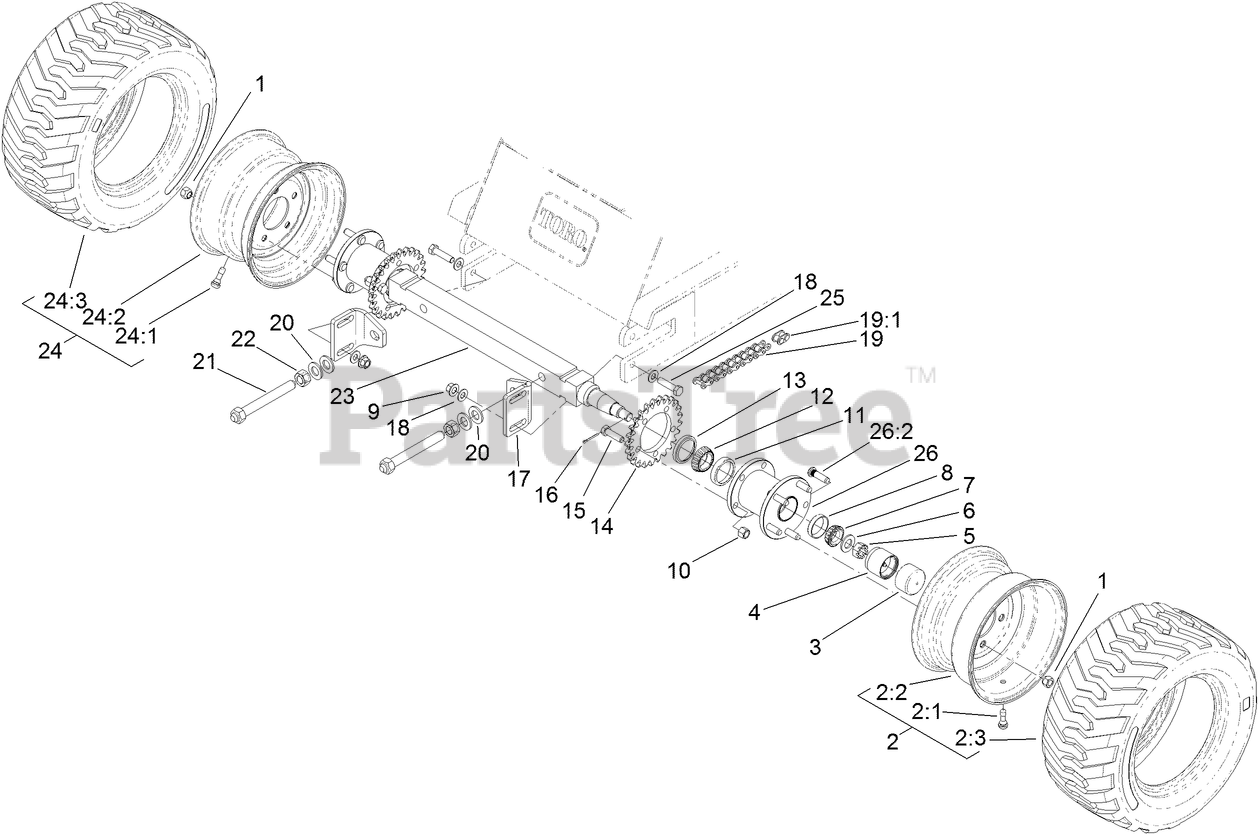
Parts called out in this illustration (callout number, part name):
1	NUT-LUG
2	LH WHEEL AND TIRE ASM
2:1	STEM-VALVE
2:2	WHEEL
3	CAP-PROTECTOR, BEARING
4	PROTECTOR-BEARING
5	NUT-HEX, SLOTTED
6	WASHER-FLAT
7	BEARING-CONE, TAPERED
8	BEARING-CUP, TAPERED
9	NUT-LOCK
10	NUT-LOCK, NI
11	CUP-BEARING, TAPERED
12	CONE-BEARING, TAPERED
13	SEAL-BEARING, WHEEL
14	SPROCKET-25T
15	SCREW-HH
16	PIN-COTTER
17	BRACKET-AXLE
18	WASHER-FLAT
19	CHAIN-ROLLER
19:1	LINK-CONNECTING
20	WASHER-FLAT
21	BOLT-TENSION
22	NUT-HEX
24	RH WHEEL AND TIRE ASM
24:1	STEM-VALVE
24:2	WHEEL
25	SCREW-HH
26	FRONT HUB ASM
26:2	STUD-TYPE, DRIVE
